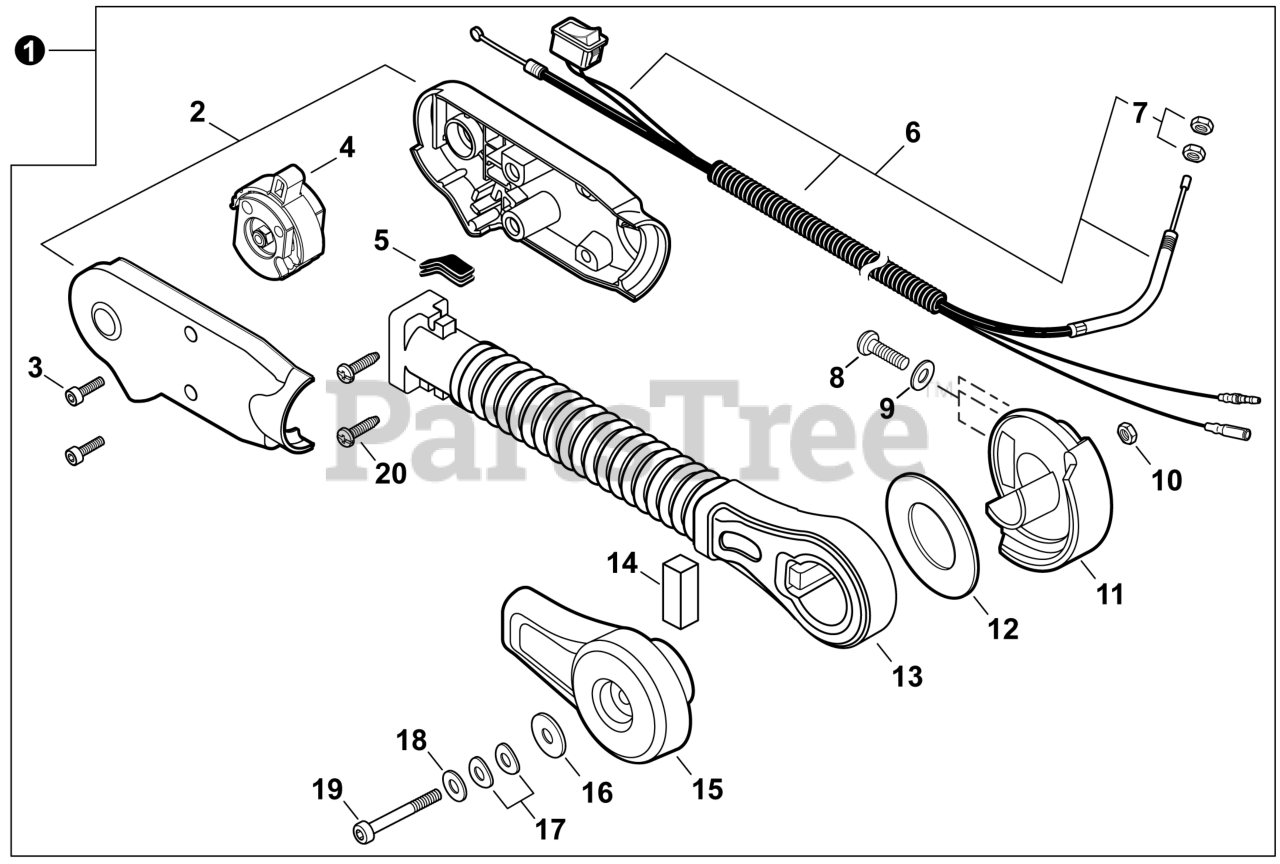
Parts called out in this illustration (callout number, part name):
1	THROTTLE CONTROL KIT - HIP MOUNT
2	GRIP SET, THROTTLE
3	BOLT, TORX 5x16
4	CONTROL, THROTTLE
5	GROMMET
6	CABLE ASSY, CONTROL
8	BOLT, TORX 5x20
9	WASHER 5.5x16x0.8
10	NUT, LOCK M6
11	BRACKET, ARM - INNER
12	WASHER 45
13	ARM, THROTTLE CONTROL
14	SEAL, DUST - FOAM
15	BRACKET, ARM - OUTER
16	WASHER 6.6x20x1.6
17	WASHER, FRICTION 6.6x14.3
18	WASHER 6.5x15.5x0.6
19	BOLT, TORX 6x75
